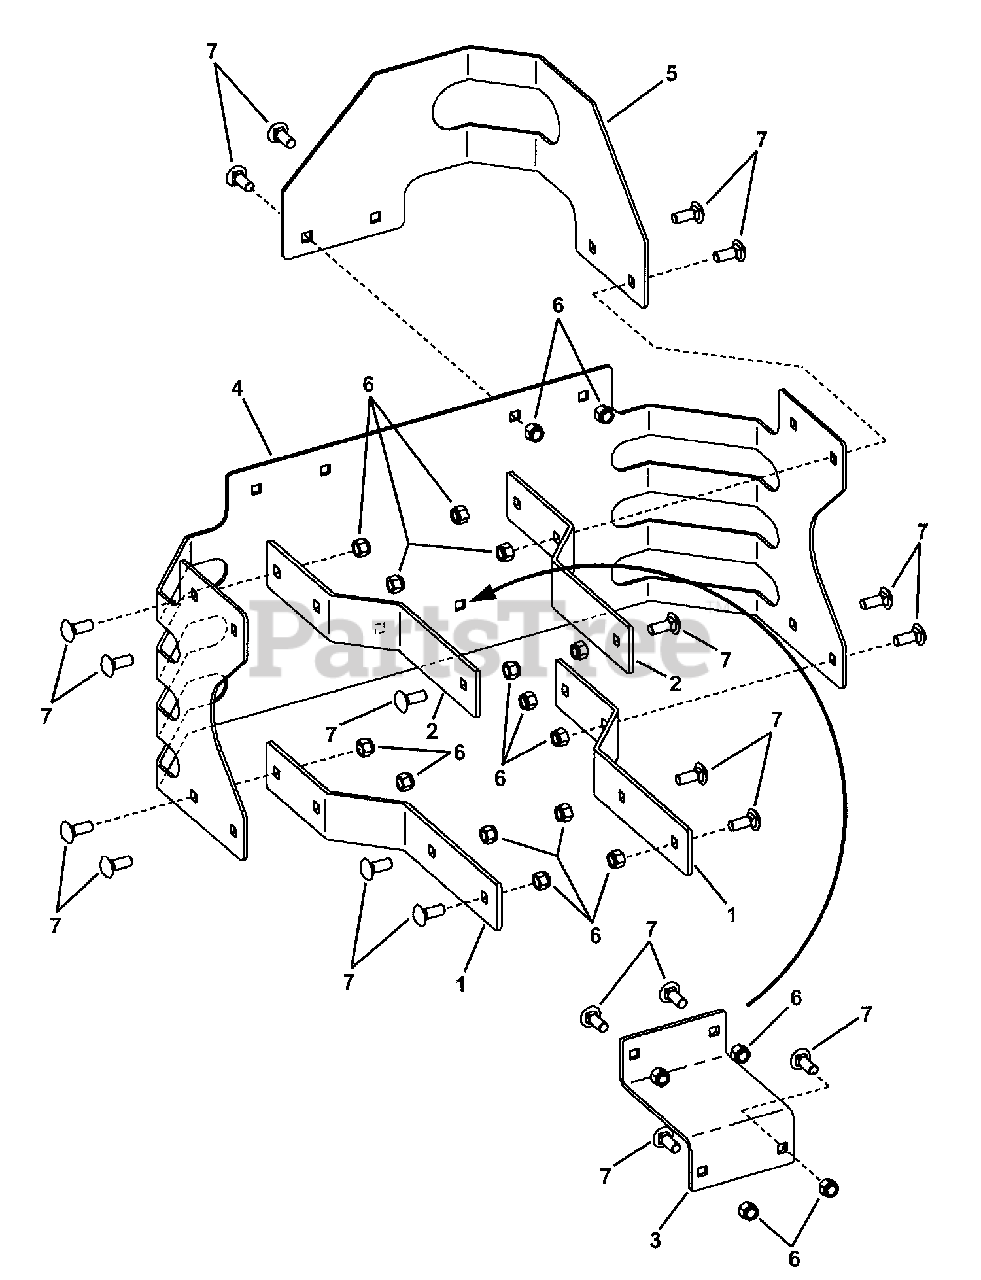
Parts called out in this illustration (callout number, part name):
1	BRACKET, Lower Guard Mount
2	BRACKET, Upper Guard Mount
3	REAR SUPPORT, Muffler Guard
4	BACK PLATE, Muffler Guard
5	GUARD, Muffler
6	NUT, 3/8-16 HEX NYLON LOCK
7	BOLT, 3/8-16 x 1" Square Neck Carriage, GR 5
